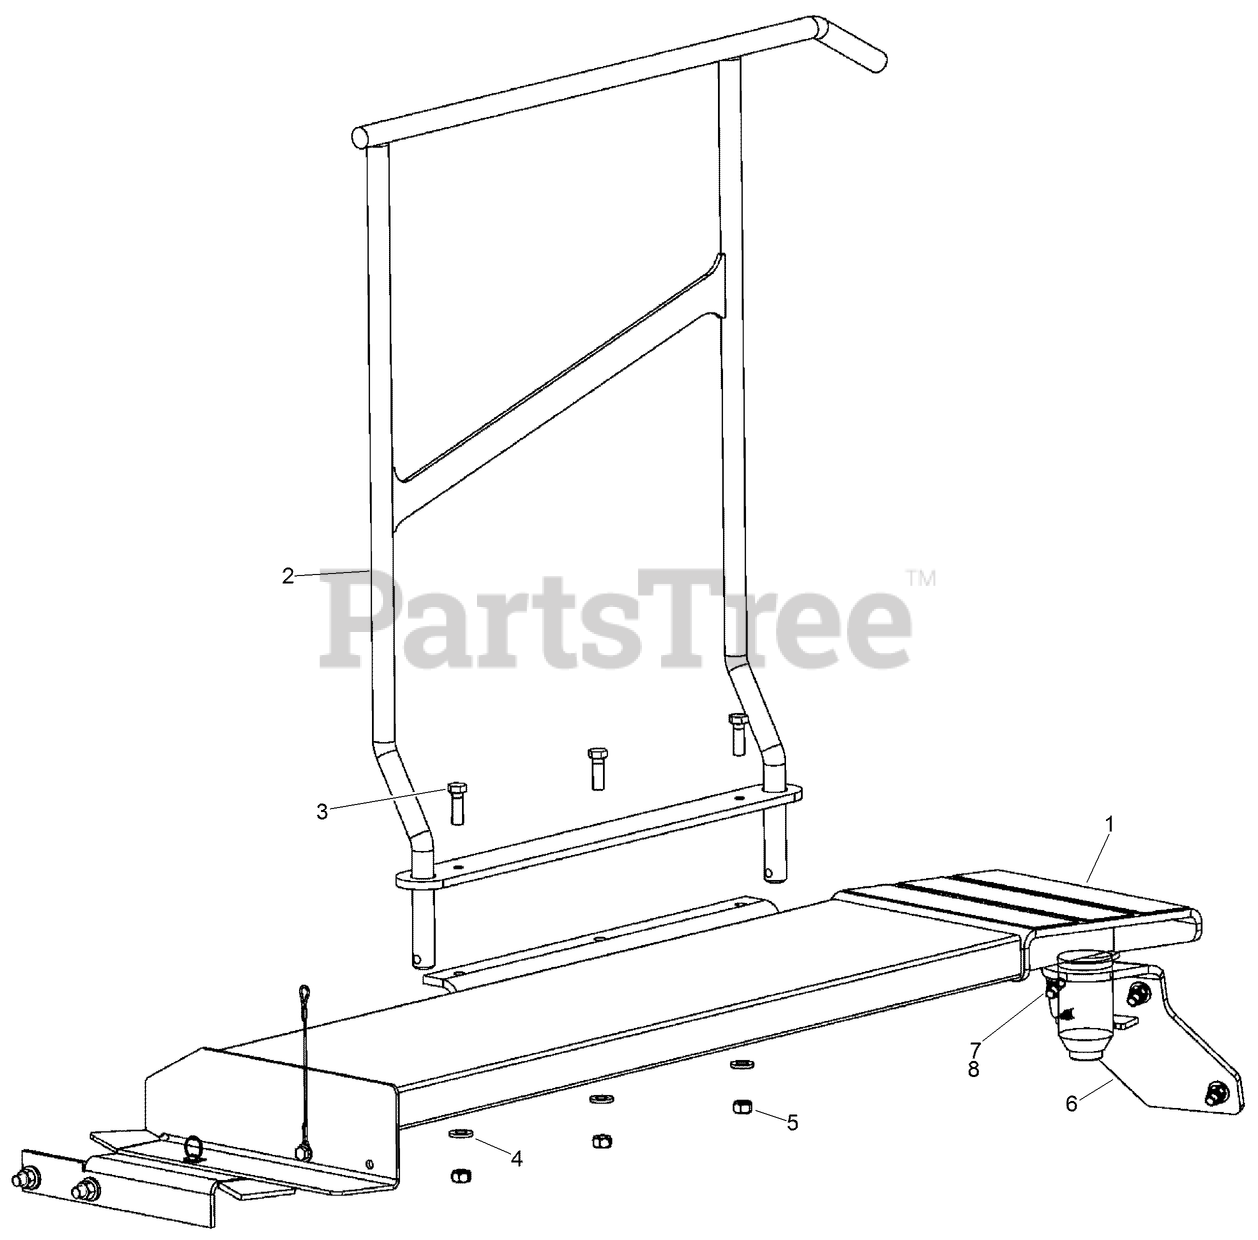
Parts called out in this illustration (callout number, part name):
1	CATWALK ASM
2	ASSEMBLY - Handrail
3	SCREW-HH
4	WASHER-FLAT
5	NUT-LOCK, HEX
6	WELDMENT - Mounting, Walkway Bracket
8	NUT-HHF, LOCK
